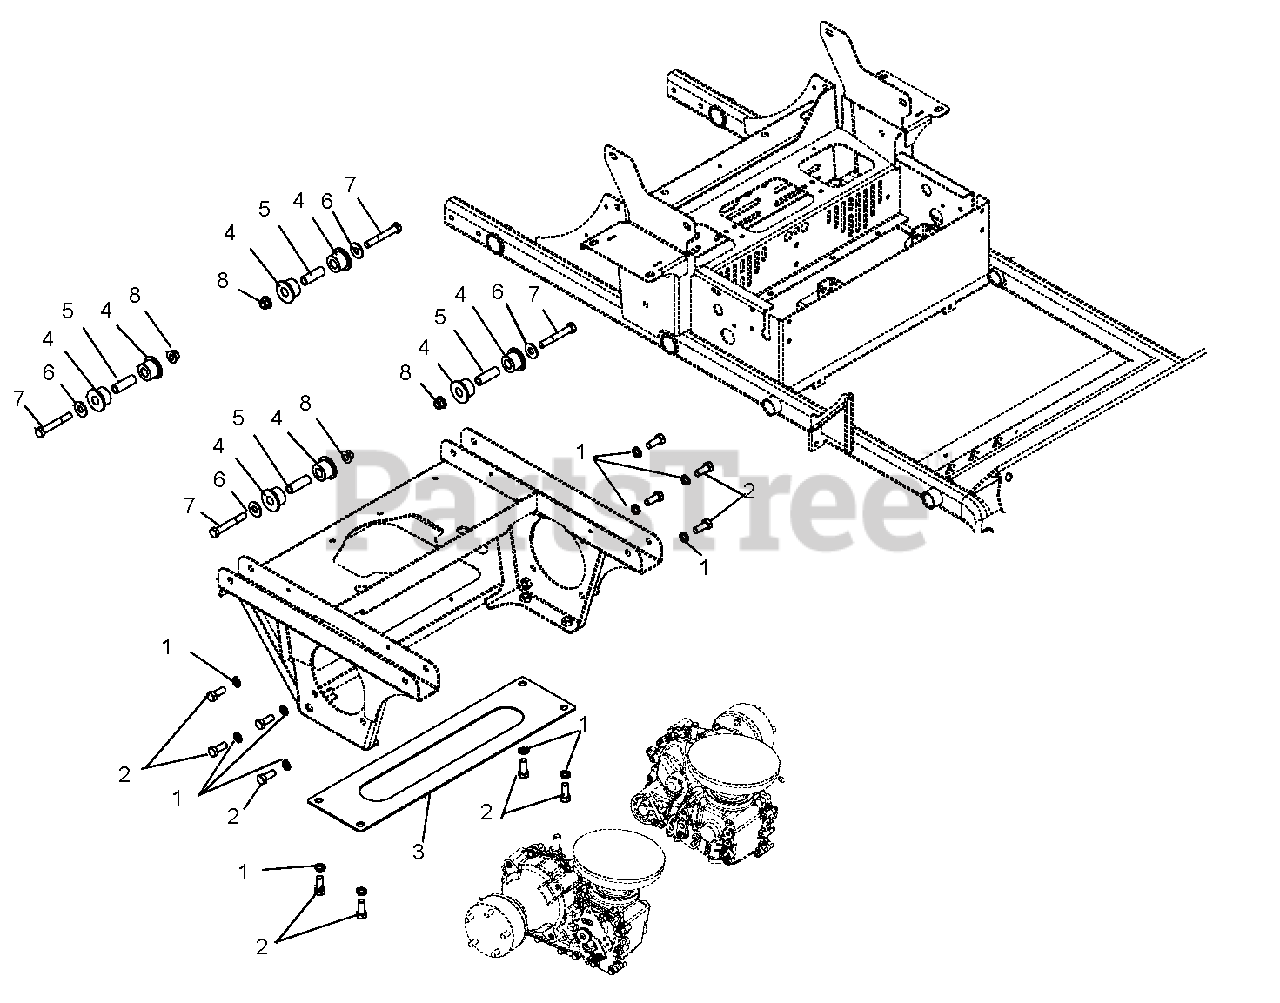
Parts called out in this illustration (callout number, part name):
1	Washer, Lock .50 x .125 REG YWZC
2	Bolt, Hex .50-13 x 1.25 GR5 YWZC
3	Plate, Transmission Connecting
4	Bushing, Flange .75 x 1.51 x 1.13 x 2.0 URE
5	Bushing, Sleave .50 x .75 x 2.23
6	Washer, Flat Steel.563 x 1.38 x .109YWZC
7	Bolt, Hex .50-13 x 3.50 GR5 YWZC
8	Nut, Locking Nylon-Flange .50-13 YWZC
